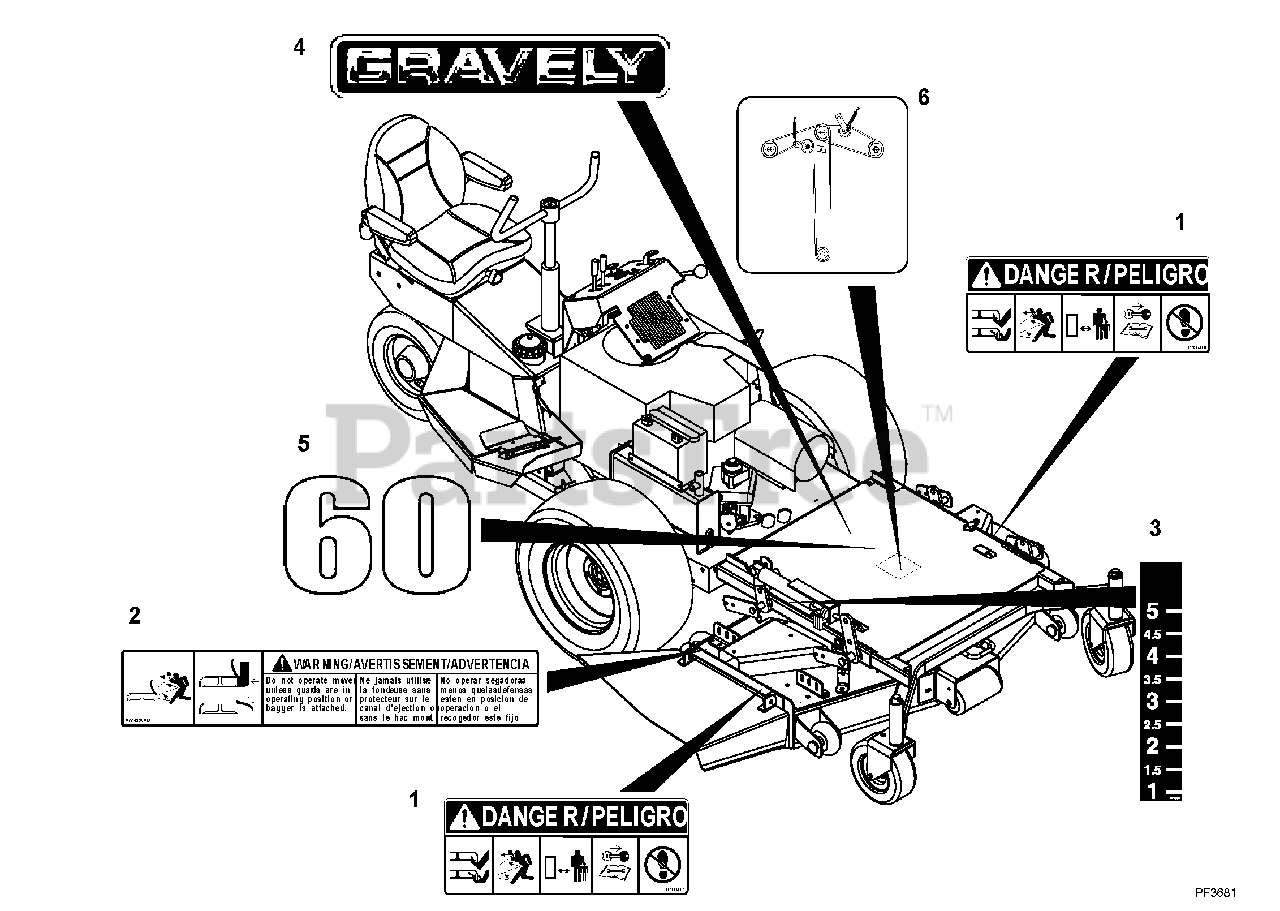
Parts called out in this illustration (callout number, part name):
1	Decal, Mower Pan Head Danger
2	Decal, Warning
3	Decal, Width of Cut
4	Decal-15" Gravely Logo
5	Decal, 60
6	Decal, Belt Diagram (016)
